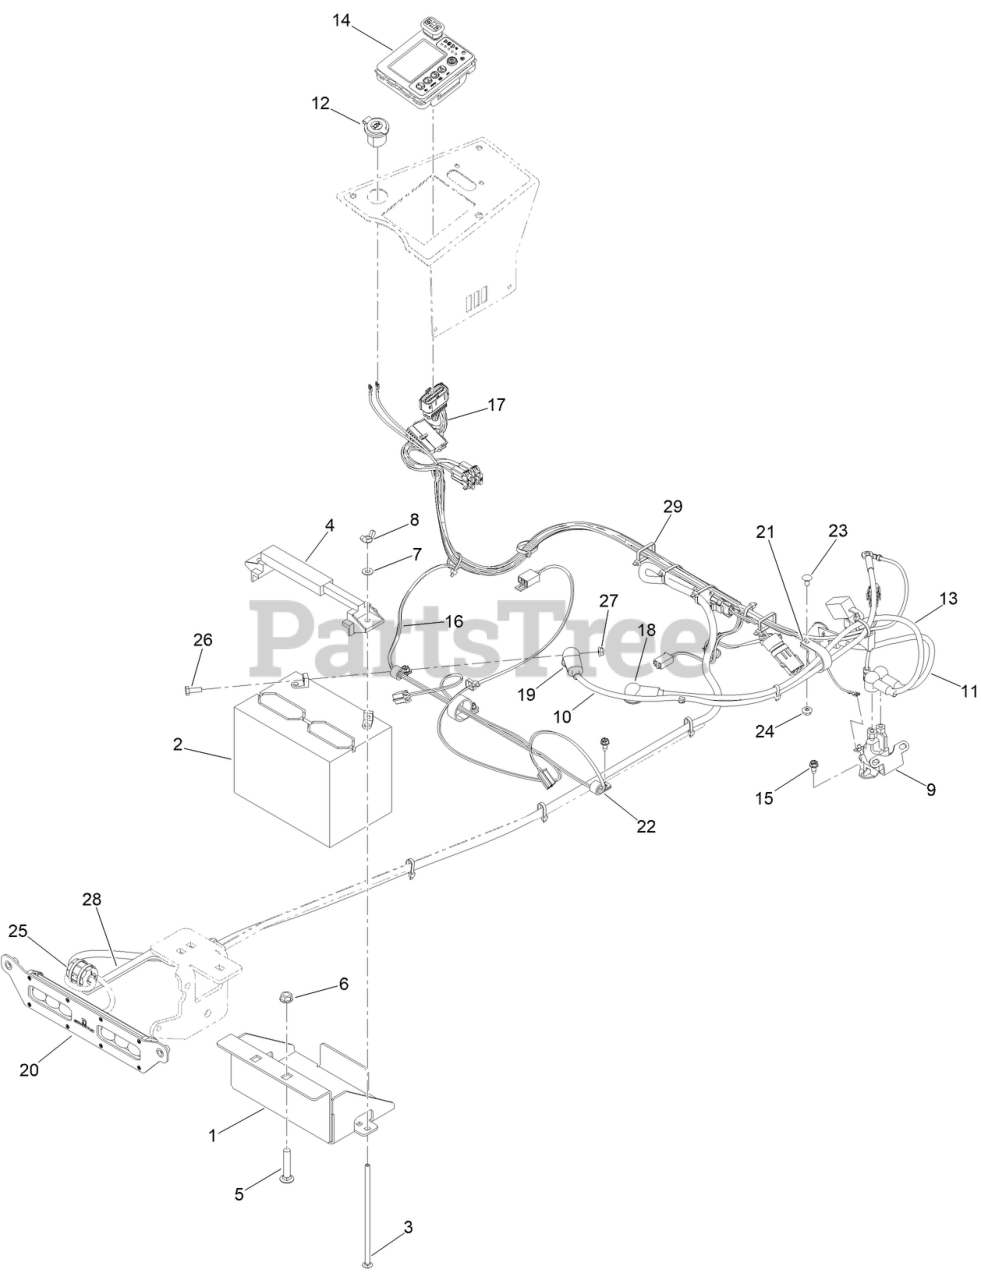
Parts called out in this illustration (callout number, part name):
1	MWR BATTERY BOX BLACK
2	12 VOLT START BATTERY 300CCA
3	1/4-20 X 7 CARRIAGE BOLT ZINC
4	BATTERY HOLD DOWN
5	SCREW-CARR
6	3/8-16 HEX FLANGE NUT W/SERR ZINC YELLOW
7	WASHER-FLAT
8	NUT-WING
9	HEAVY DUTY START SOLENOID
10	MWR NEGATIVE CABLE 28
11	MWR START WIRE 12
12	12 VOLT AUXILLIARY PLUG
13	MWR POSITIVE BATTERY CABLE 25IN
14	CONSOLE-CONTROL
15	SCREW-HWH
16	BRIGGS 25HP/27HP/ 726CC HARNESS
17	HARNESS-JUMPER
18	3.15 LGTH STRAIGHT INSUL TERM COVER RED
19	STRAIGHT INSULATING TERMINAL COVER
20	SPLIT BEAM W/NON-LIGHTD HELMET LIGHT BAR
21	1-1/4IN CUSHIONED LOOP CLAMP BLACK
22	CLAMP-R
23	SCREW-CARR
24	1/4-20 HEX FLANGE NUT
25	FAIR-RITE ROUND CABLE SNAP-IT SIZE B
26	SCREW-HH
27	NUT-HF
28	FAIR-RITE BRACKET PAINTED
29	TIE-CABLE
